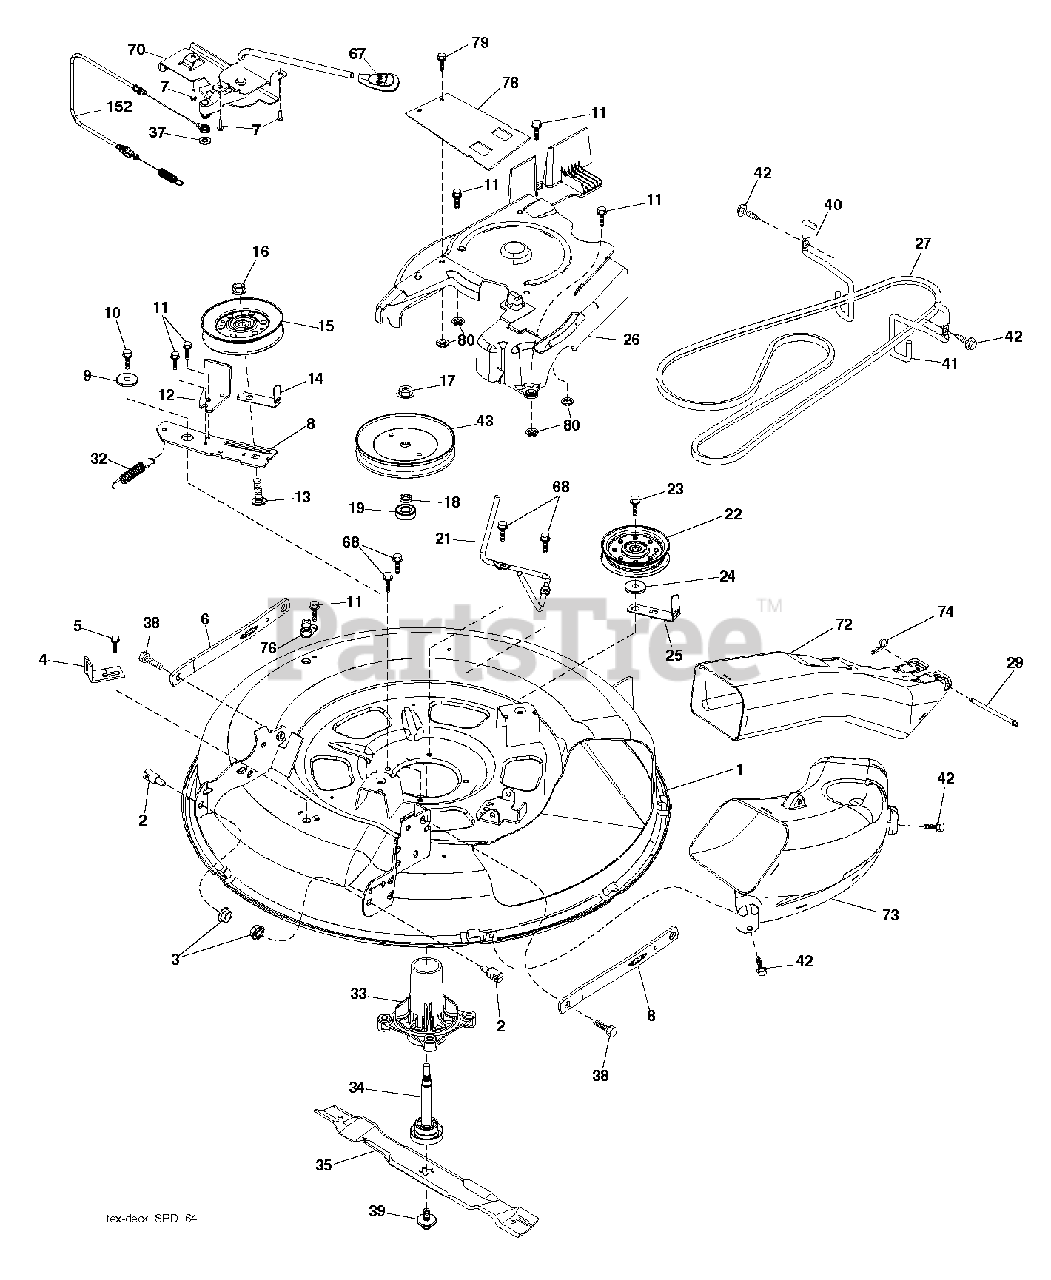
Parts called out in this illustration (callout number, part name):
2	STUD.FASTNER.W/ANTI-ROTATE
3	NUT LOCK HEX FLANGE 5/16-18
5	BOLT.5/16HEX.WHS.HD
6	ARMS.SUSP.MOWER.REAR.SRD
7	SCREW.#10 X 0.750.BOS THREAD
9	SPACER.RETAINER
10	SCREW 3/8-16X1
11	SCREW.1/4-20X5/8
12	ARM BRAKE MOWER RH
13	BOLT.3/8-16X1.50
14	KEEPER, BELT IDLER
15	PULLEY.IDLER.4.25
16	NUT LOCK FLG 3/8-16 UNC
17	NUT.FLANGE.LOCK.TOP
18	WASHER.SPACER.MANDREL
22	PULLEY.IDLER.FLAT.46.PR.DR.
23	SCREW LT
27	V-BELT.DRIVE.MOWER.30"
32	SPRING RETURN
33	HOUSING MANDREL
34	SHAFT.ASM.MDRL.N/GREASE.38
35	BLADE.MOWER.BAGGING.30"
38	BOLT.SHOULDER
39	Screw, 7/16 X 20 X 1"
42	SCREW, 3/8-16X3/4
43	PULLEY, MANDREL 6.5 PD
67	HANDLE.CLUTCH.CABLE.LT
68	Hex Washer Head Bolt, .313-18 X 1.19
70	CLUTCH.ASM.MANUAL.LT.PRED
74	RETAINER-SPRNG RB
76	PORT.WASHOUT
79	SCREW.HI-LO.CONSOLE
80	PALNUT 1/4
152	CABLE.CLUTCH.MANUAL.
